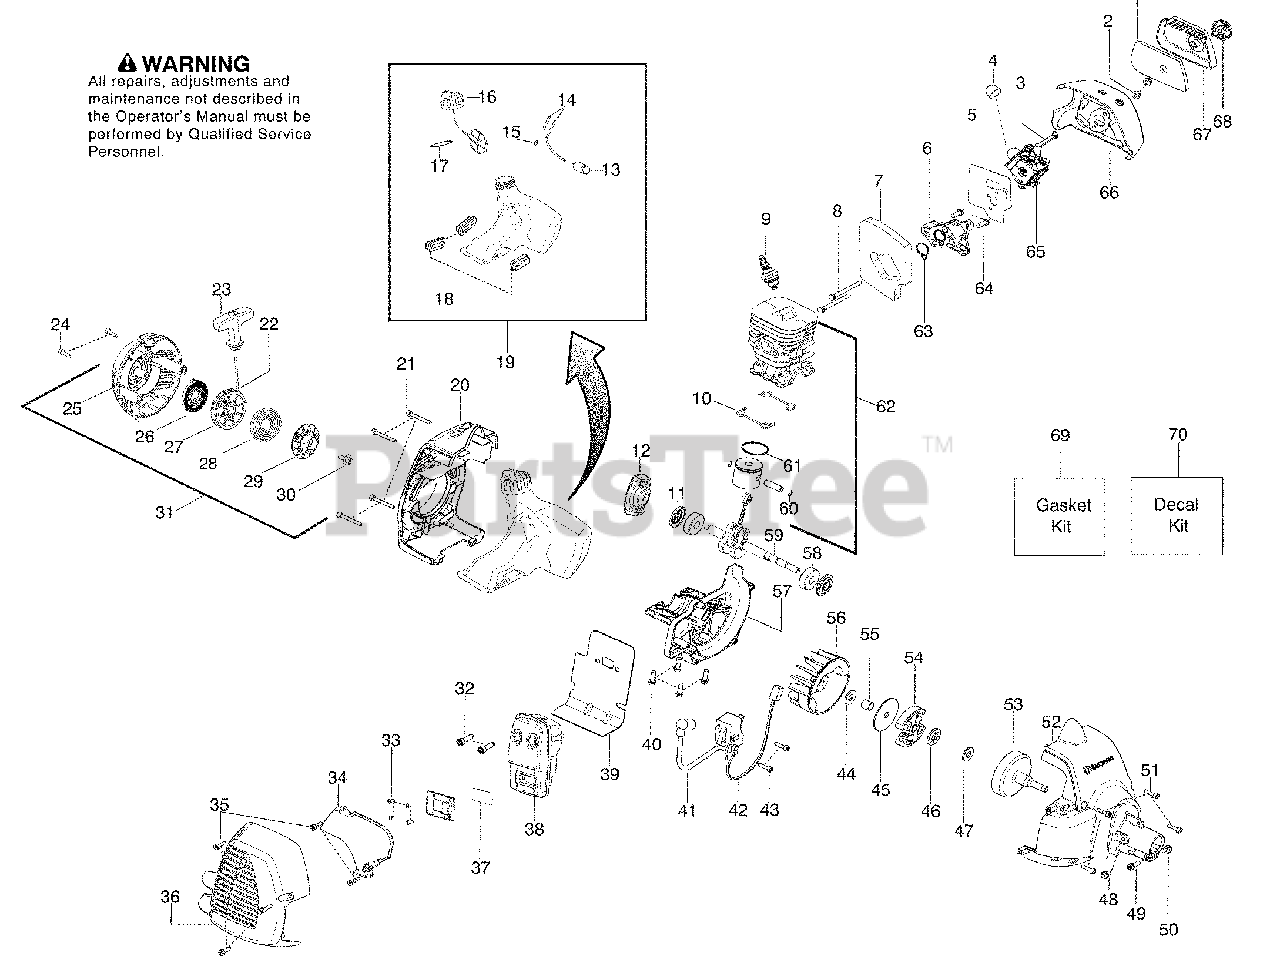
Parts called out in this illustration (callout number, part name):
2	Nut - Carb. Screw
3	Lever - Choke
4	Bulb - Purge
5	Kit - Carb. Gasket
6	Adaptor - Carb.
7	Foam – Gasket
9	Plug – Spark
10	Seal – Cylinder
11	Seal – Crankshaft
12	Assy - Starter Pawl
13	Assy - Fuel Filter
14	Kit - Fuel Line
15	Fitting - Fuel line
16	Assy - Cap w/ret.
17	O-ring - Fuel Cap
18	Isolator - Fuel Tank
19	Kit - Fuel Tank Assy.
20	Shroud - Rear
22	Kit - Rope
23	Handle - Starter
25	Hsg. - Starter w/eyelet
26	Kit - Spring
27	Kit - Starter Pulley
28	Spring - Driver
29	Pulley - Driver
31	Assy - Starter Hsg.
32	Bolt - Muffler
33	Screw
34	Shield - Heat
36	Guard - Muffler
37	Kit - Spark
38	Kit - Muffler
39	Gasket - Paper Met.
42	Assy - Leadwire
45	Washer - Clutch
46	Bearing - Thrust
47	Washer - Thrust
52	Assy - Fan Housing
53	Assy - Clutch Drum
54	Assy - Clutch
57	Crankcase - Cast
59	Assy - Crankshaft
60	Retainer - Piston Pin
61	Ring - Piston
62	Kit – Piston/Cyl.
63	Seal – adaptor
65	Kit - Carb.
66	Airbox
67	Cover - Air Box
68	Assy - Knob
69	Kit - Gasket
70	Kit - Decal
